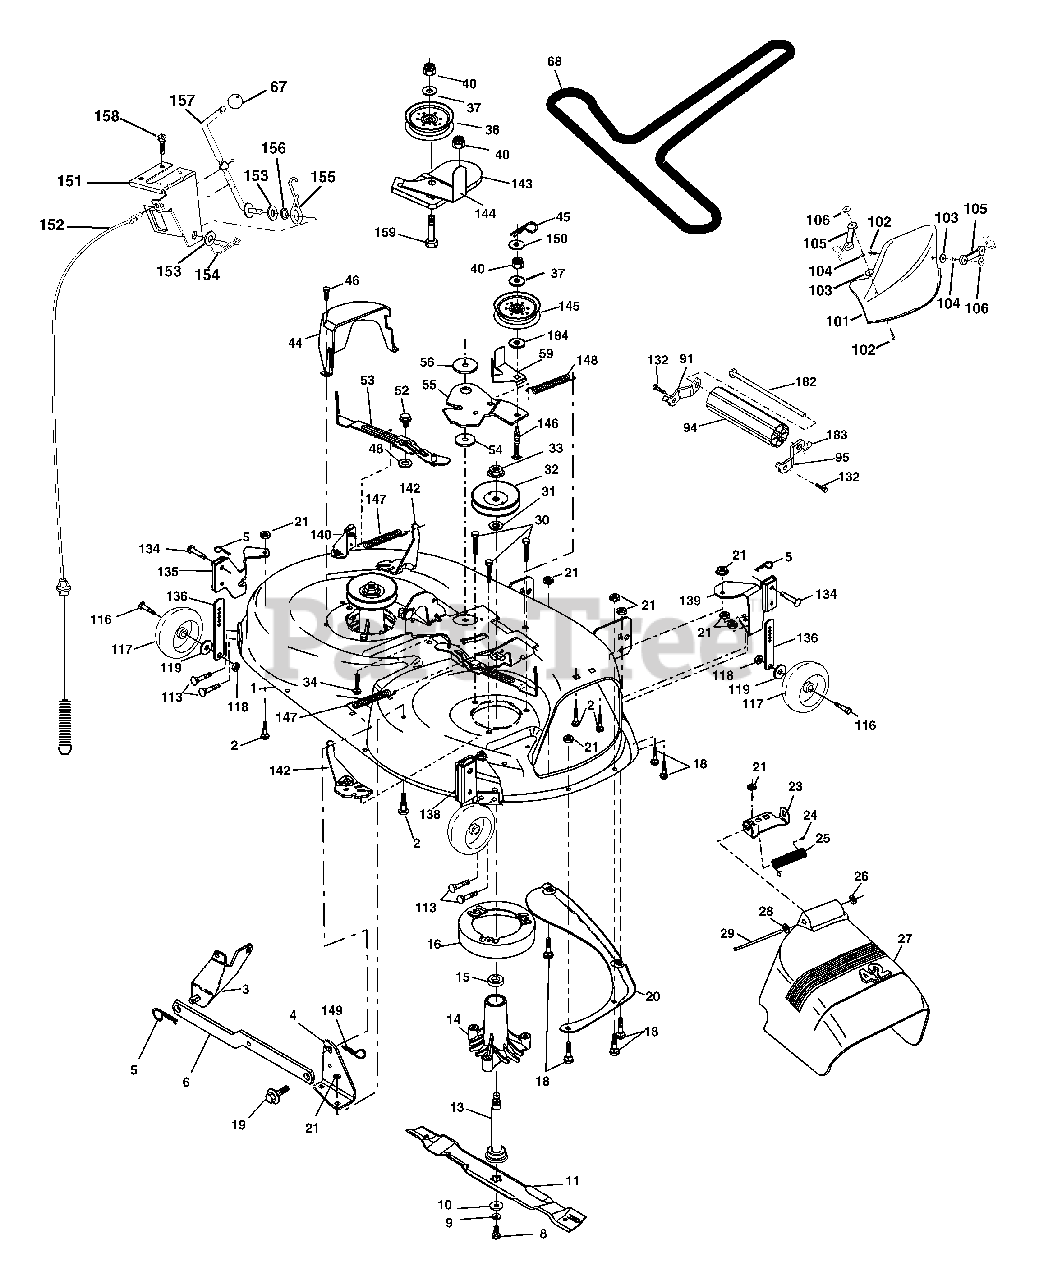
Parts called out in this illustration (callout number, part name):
1	Mower Deck Assembly, 42"
2	Bolt
3	Bracket Asm Fr. Sway Bar 3/42
4	Bracket Asm Deck 42" Sway Bar
5	Retainer Spring
6	Bar Sway Deck
8	Bolt 3/8-24 x 25 Grade 8 patched
9	Washer, Lock
10	Washer, Hardened
11	Blade, 42" Mulching Std
11	Blade, 42" Mulching Premium
11	Blade, 42" Hi-Lift
13	Shaft Assembly, Mandrel, Vented
14	Housing, Mandrel, Vented
15	Bearing, Ball, Mandrel
16	Stripper, Vented Mower Deck
18	Bolt, Carriage 5/16-18 x 5/8
19	Bolt, Shoulder
20	Baffle, Vortex
21	Nut
23	Bracket, Deflector Mower 42"
24	Cap, Sleeve 80 x 112 Blk Mower
25	Spring, Torsion, Deflector 2 52
26	Nut, Push Phos & Oil
27	Shield, Deflector 42" Blk
28	Washer 11/32 x 5/8 x 16 Gauge
29	Rod, Hinge 42" 6 75 W/G
30	Screw Thdrol Washer Head
31	Washer, Spacer Mower Vented
32	Pulley, Mandrel
33	Nut, Toplock Flange
34	Bolt
36	Pulley, Idler, Flat
37	Washer 13/32 x 13/16 x 16 Ga.
40	Nut
44	Guard, Mandrel, LH
45	Retainer
46	Screw, Thdrol 1/4-20 x 5/8 T
48	Washer, Hardened
52	Bolt, Shoulder 5/16-18 Unc
53	Arm Assembly, Pad, Brake
54	Washer, Hardened
55	Arm, Idler
56	Spacer, Retainer
59	Guard TUV Idler
67	Knob
68	V-Belt, 42" Mower
91	Bracket Noseroller LH
94	Roller Nose
95	Bracket Noseroller RH
101	Cover Mulching
102	Screw 10-24 x 5/8
103	Washer #10
104	Washer Lock #10
105	Latch Asm.
106	Nut Weld
113	Screw 5/16-18 x 3/4
116	Bolt Shoulder 3/8-16 x 3-5/8
117	Wheel Gauge
118	Nut 3/8-16
119	Washer 3/8 x 7/8 x 14 Ga.
132	Screw 3/8-16 x 3/4
134	Pin Head Rivet
135	Bracket Asm. LH Rear
136	Bar Adjusting
138	Bracket Asm. RH Rear
139	Bracket Asm. RH Front
140	Bracket Asm. LH Front
142	Arm Spring Brake Mower
143	Bracket Arm Idler 42"
144	Keeper Belt 42" Clutch Cable
145	Pulley Idler Flat
146	Bolt Carriage Idler
147	Spring Extension
148	Spring Return Idler
149	Retainer Spring Yellow
150	Washer 9/32 x 3/4 x 16 Ga.
151	Bracket Clutch Cable
152	Clutch Cable 42"
153	Washer Flat 3/8" Type B
154	Spring Retainer
155	Spring Retention LVR CLTCH CAB
156	Spacer Clutch Cable
157	Rod Clutch Cable 3/8"
158	Screw Hex Thd Cut 1/4-20 x 1/2
159	Bolt Rdhd Sqn 3/8-16 Unc x 1-3/4
182	Rod Roller Nose
183	Retainer Spring
184	Washer 13/32 x 7/8 x 10 Ga.
